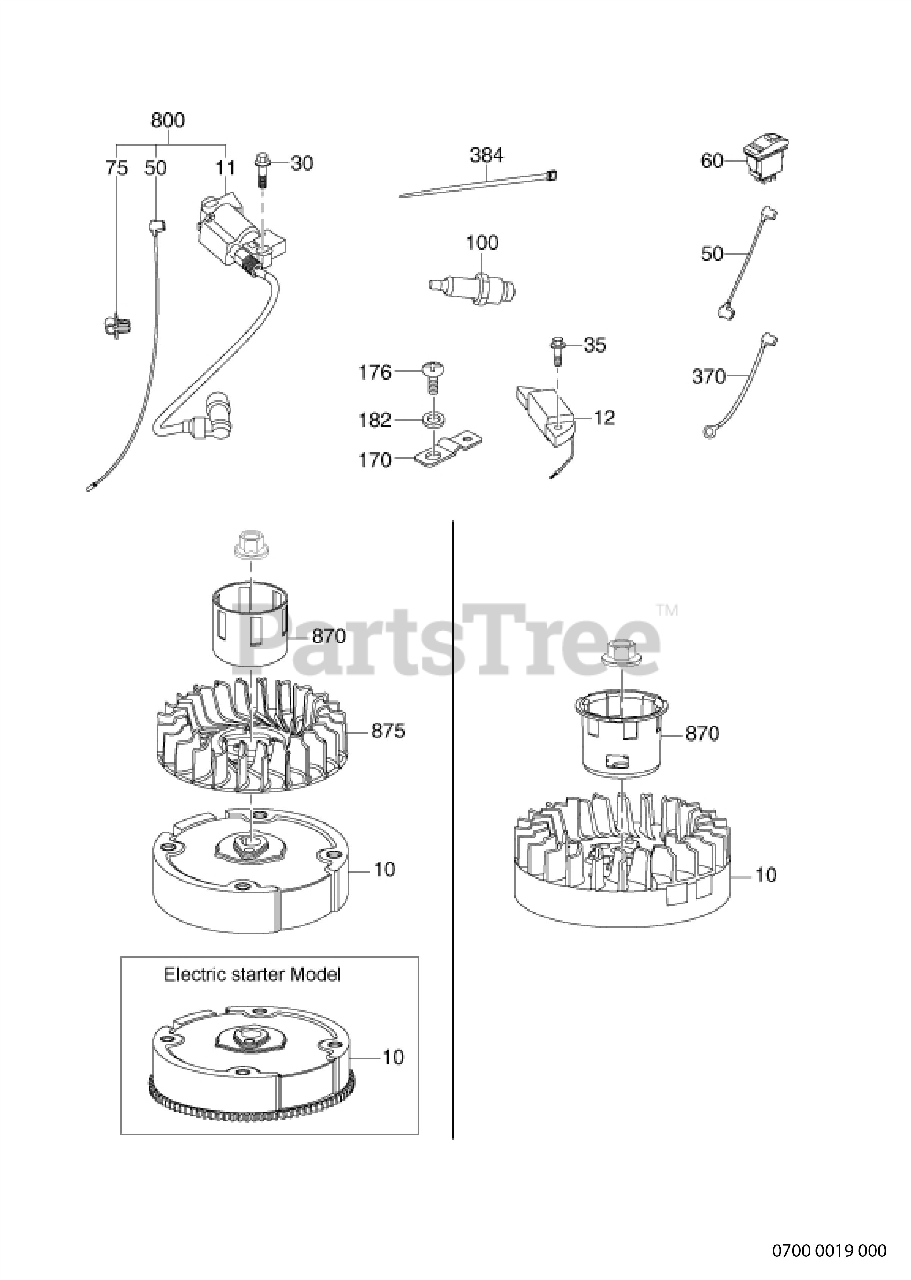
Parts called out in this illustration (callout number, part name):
10	FLY WHEEL
30	BOLT
100	SPARK PLUG
